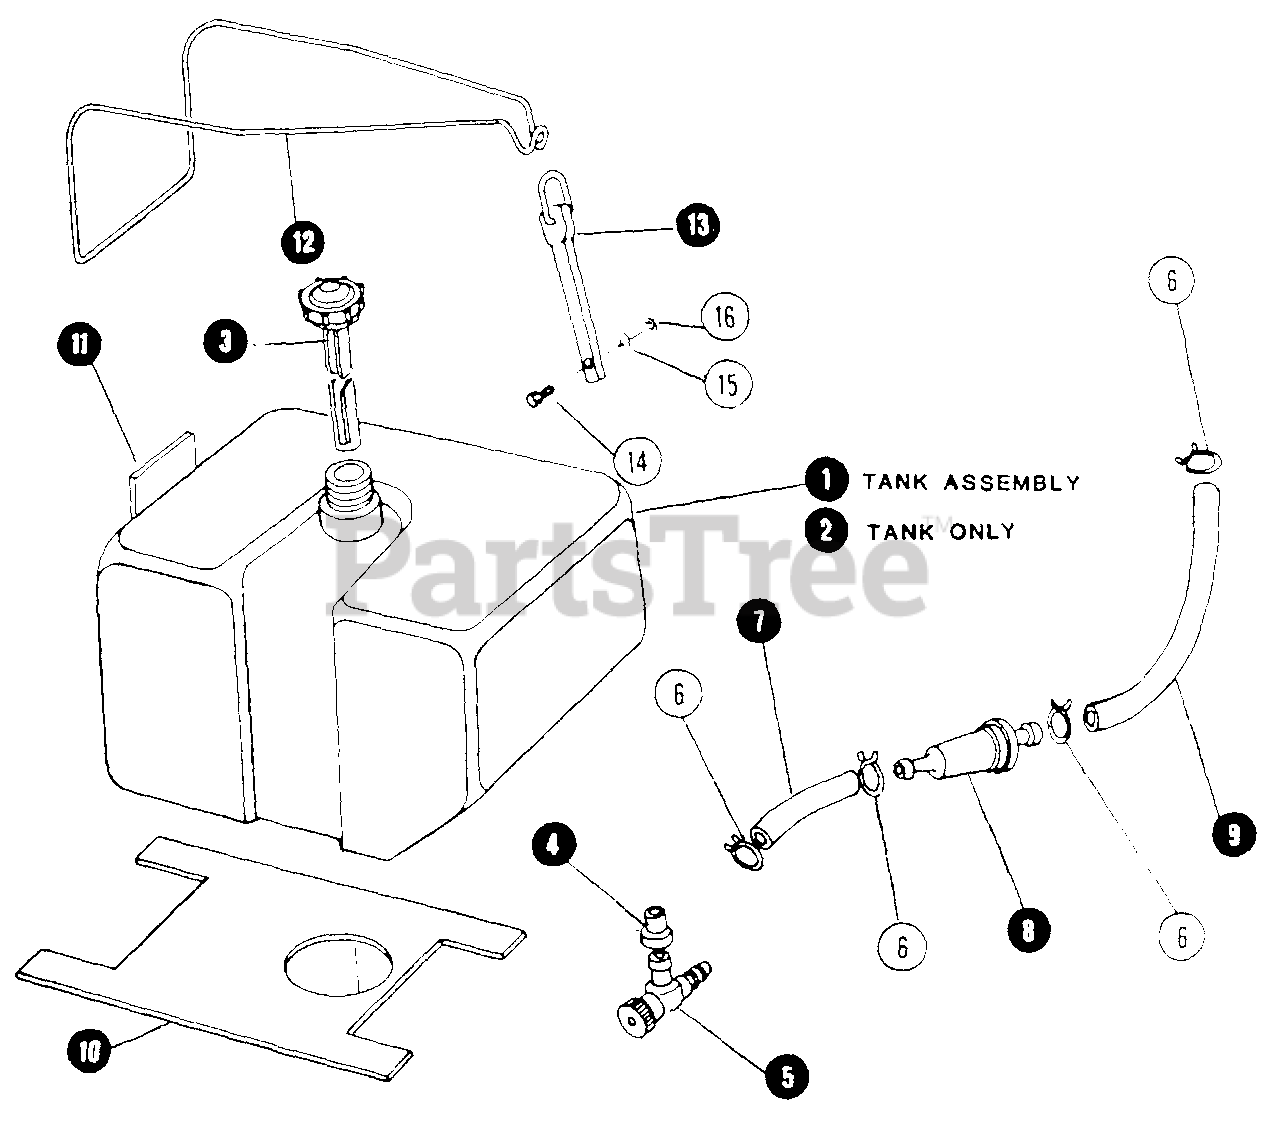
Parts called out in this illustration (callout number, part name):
1	FUEL TANK ASSEMBLY
2	TANK, FUEL
3	CAP, FUEL TANK
4	GROMMET
5	VALVE, FUEL SHUTOFF
6	CLAMP, HOSE
7	LINE, UPPER FUEL - 7" LONG
8	FILTER, IN-LINE FUEL
9	LINE, LOWER FUEL - 13" LONG
10	PAD, TANK INSULATOR
11	PAD, TANK
12	CLAMP, TANK
13	RETAINER, TANK
14	BOLT, 1/4C x 5/8 FLANGE LOCK
15	WASHER, 9/32 FLAT
16	NUT, 1/4C HEX LOCK
